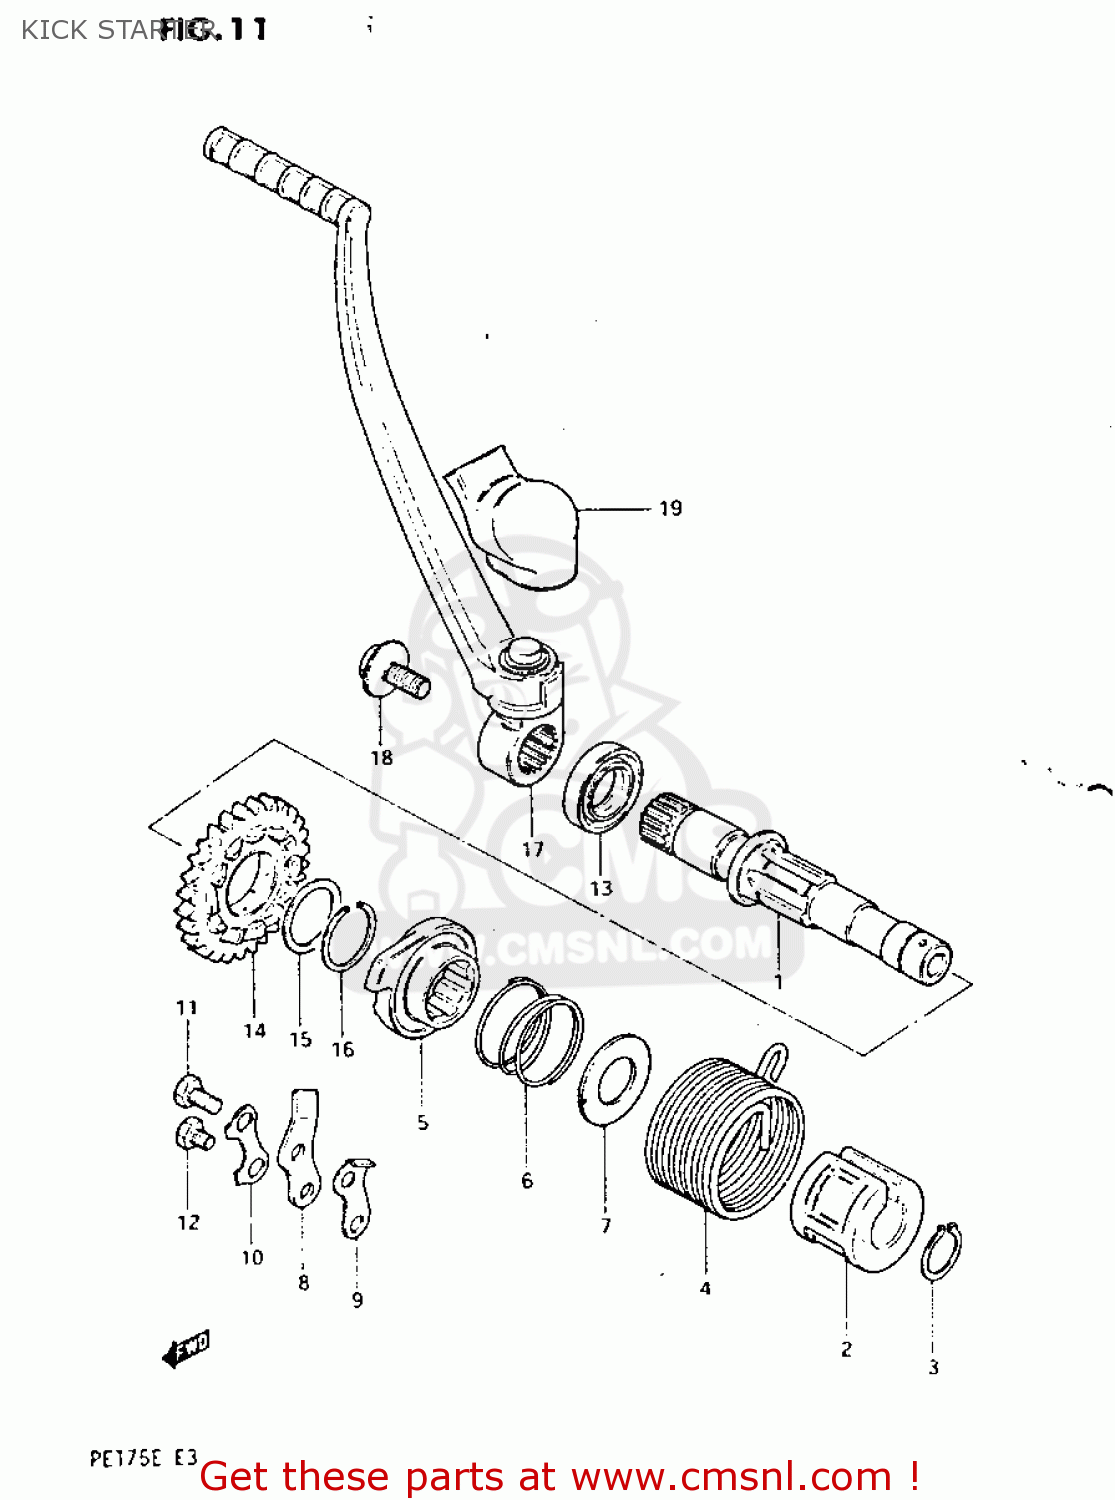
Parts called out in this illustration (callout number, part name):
1	SHAFT,KICK STARTER
2	GUIDE,KICK STARTER SFT SPRING
3	CIRCLIP
4	SPRING
5	STARTER,KICK
6	SPRING
7	WASHER
8	GUIDE,KICK STARTER
9	STOPPER,KICK STARTER
10	WASHER
11	BOLT
12	BOLT
13	SEAL,OIL(20X27X5)
14	GEAR,KICK STARTER DRIIVE
15	SHIM
16	CIRCLIP
17	LEVER ASSEMBLY,KICK STARTER
18	BOLT(8X14)
19	COVER,KICK STARTER LEVER JOINT
